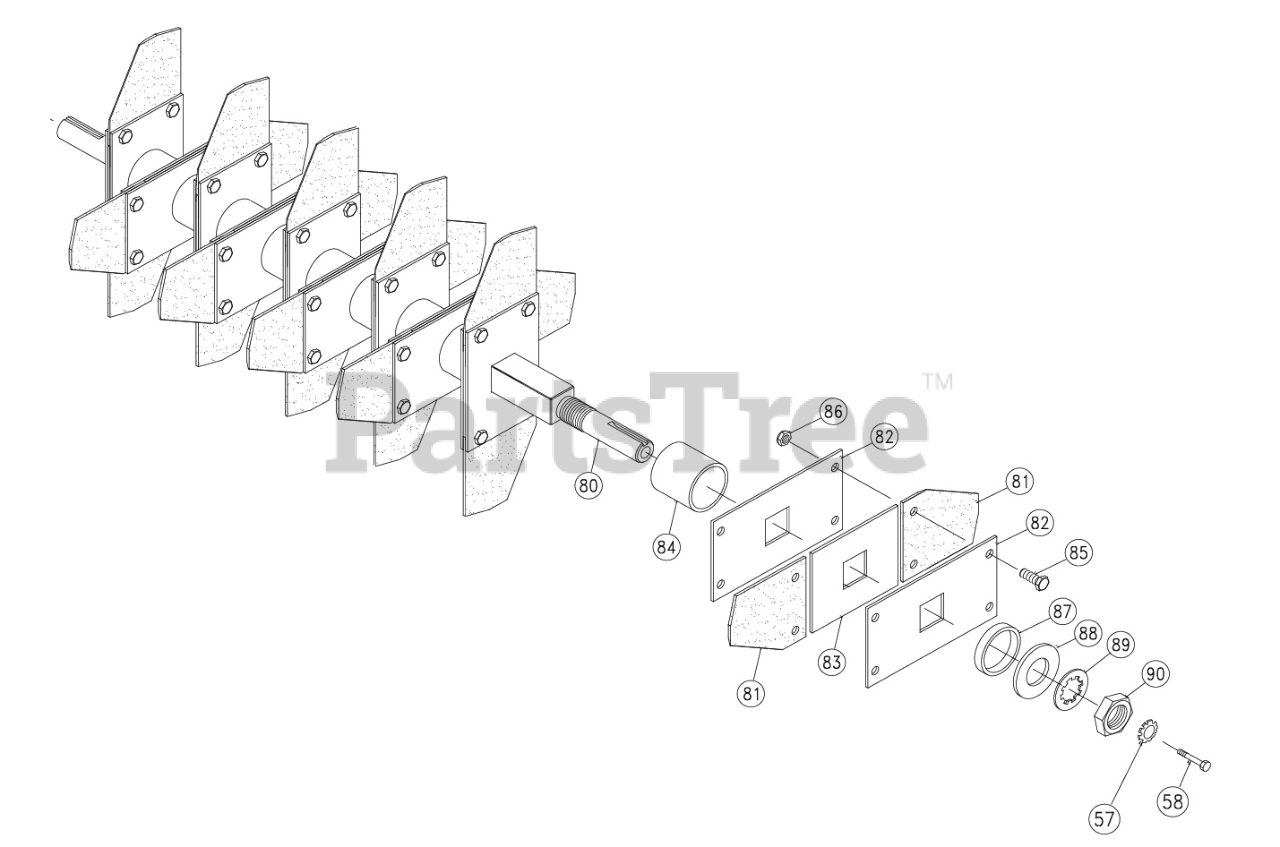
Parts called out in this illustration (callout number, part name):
57	WASHER LOCK 5/16" TWISTED TOOTH HEAVY
58	SCREWCAP 5/16"-24 X 1" GR.8 ZP W/PATCH
80	SHAFT SLICING
81	BLADE SLICING REEL
82	PLATE BLADE MOUNT 9"
83	PLATE SPACER BLADE 9"
84	SPACER BLADE ASSY
85	SCREWCAP 1/4"-20X3/4" HCS ZP
86	NUT LOCK 1/4- 20 2 WAY
87	COLLAR SPACER
88	WASHER 0.937 "X 1.75" X 0.119"
89	WASHER LOCK 7/8" INT TOOTH
90	NUT JAM 7/8"-14
